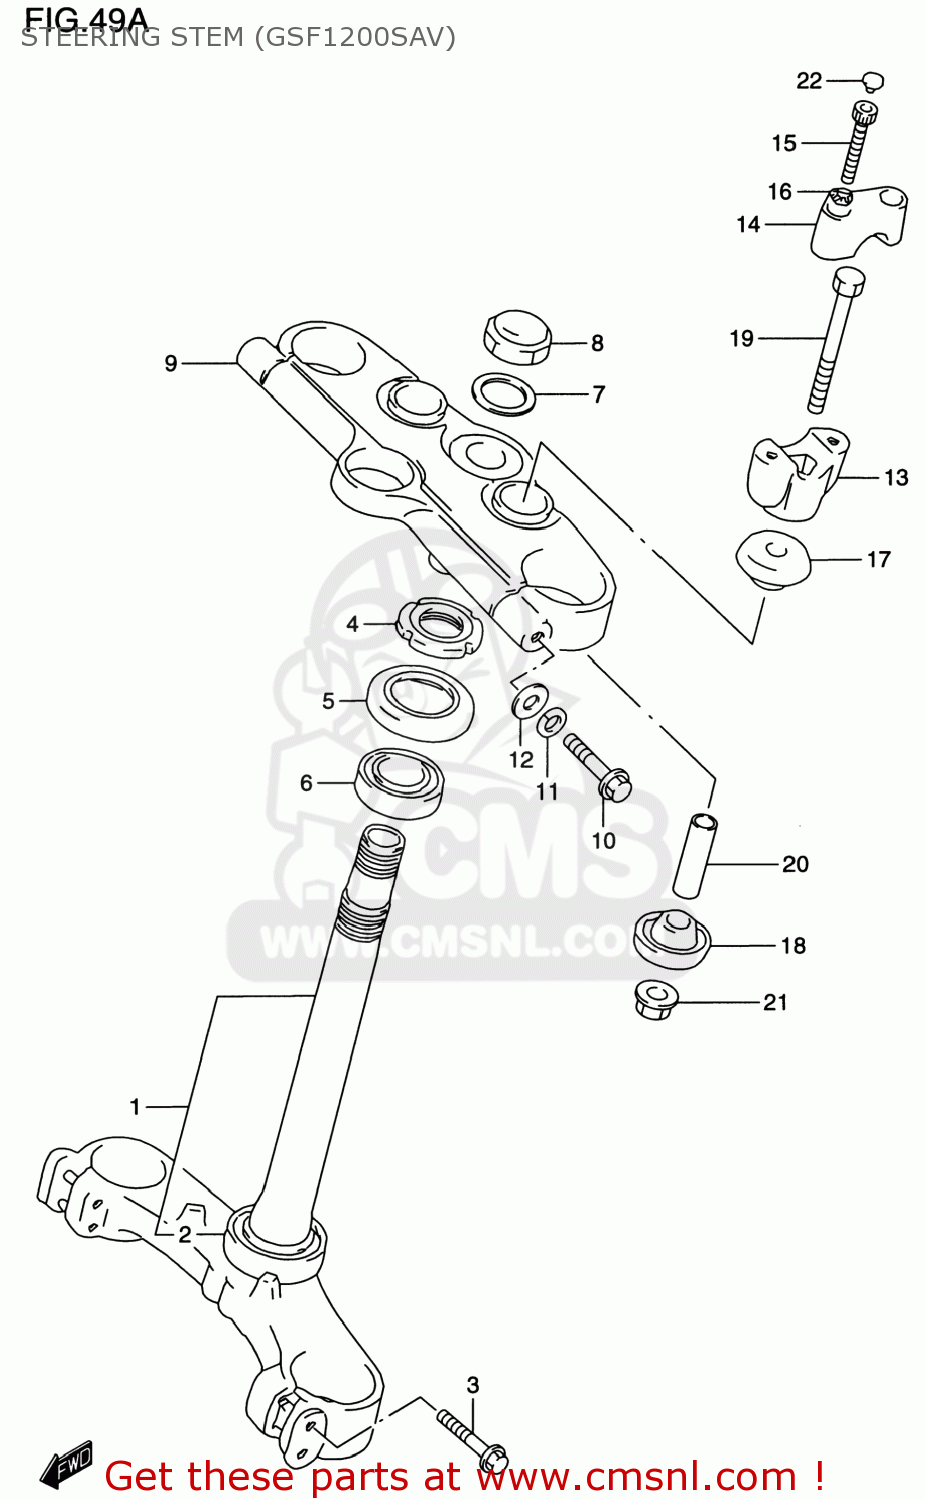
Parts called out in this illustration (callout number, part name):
1	STEM,STEERING
2	BEARING(30X55X17)
3	BOLT
4	NUT,STEERING STEM(25X44X10)
5	SEAL,STEERING UPR DUST
6	BEARING(25X47X15)
7	WASHER(22.5X32X1.6)
8	NUT,CAP
9	HEAD,STEERING STEM
10	BOLT
11	WASHER,LOCK
12	WASHER
13	HOLDER,HANDLE UNDER
14	HOLDER,HANDLE UPR
15	BOLT
16	WASHER
17	CUSHION,RUBBER UPR
18	CUSHION,RUBBER UNDER
19	BOLT,HANDLE HOLDER(10X70)
20	SPACER
21	NUT
22	CAP(OD:11)
